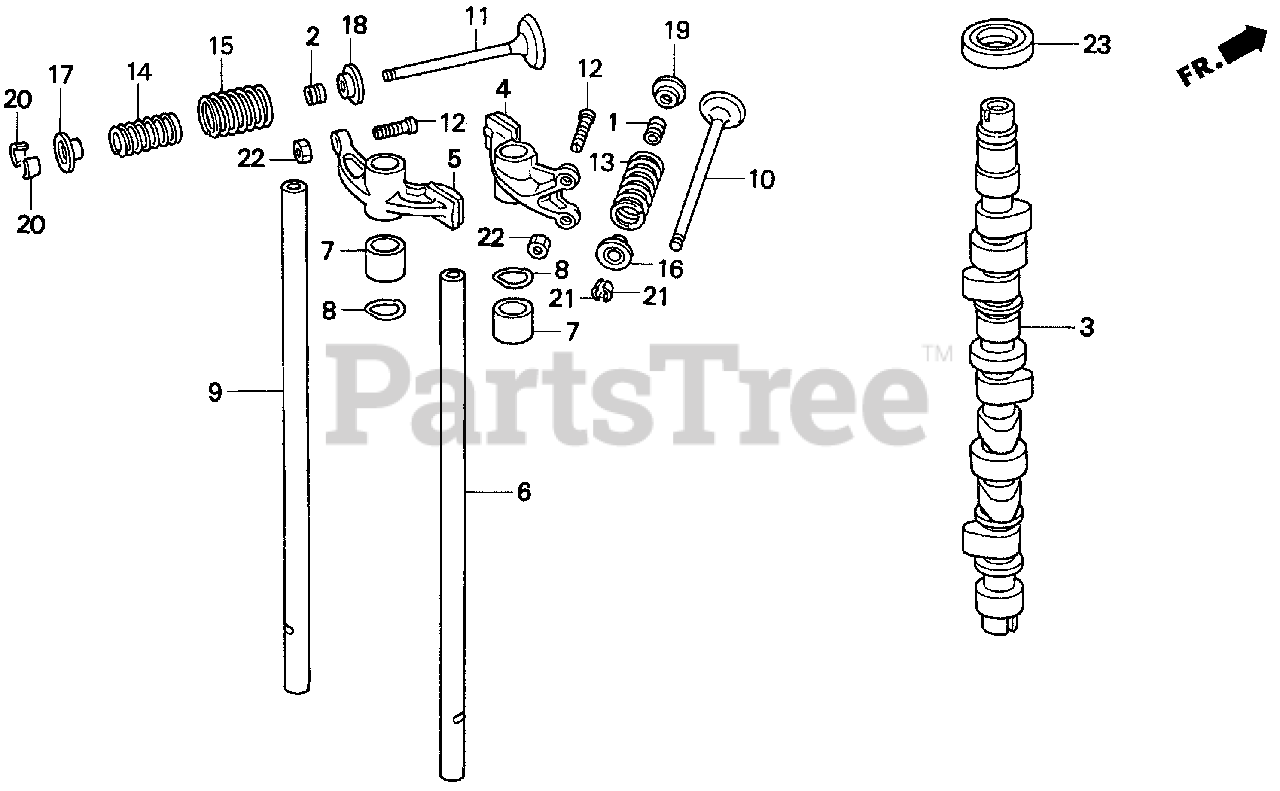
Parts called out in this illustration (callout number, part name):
1	SEAL, VALVE STEM
2	SEAL, VALVE STEM (NOK)
4	ARM ASSY., IN. ROCKER
5	ARM, EX. ROCKER
6	SHAFT, IN. ROCKER ARM
7	COLLAR, ROCKER
8	WASHER, WAVE
9	SHAFT, EX. ROCKER
10	VALVE, IN.
11	VALVE, EX.
12	SCREW, TAPPET ADJUSTING
13	SPRING, IN. VALVE
14	SPRING, EX. VALVE (INNER)
15	SPRING, EX. VALVE (OUTER)
16	RETAINER, VALVE SPRING
17	RETAINER, VALVE SPRING
18	SEAT, VALVE SPRING
19	SEAT, VALVE SPRING
20	COTTER, VALVE
21	COTTER, VALVE (FUJI VALVE)
22	NUT, TAPPET ADJ.
23	OIL SEAL (31X46X7)
